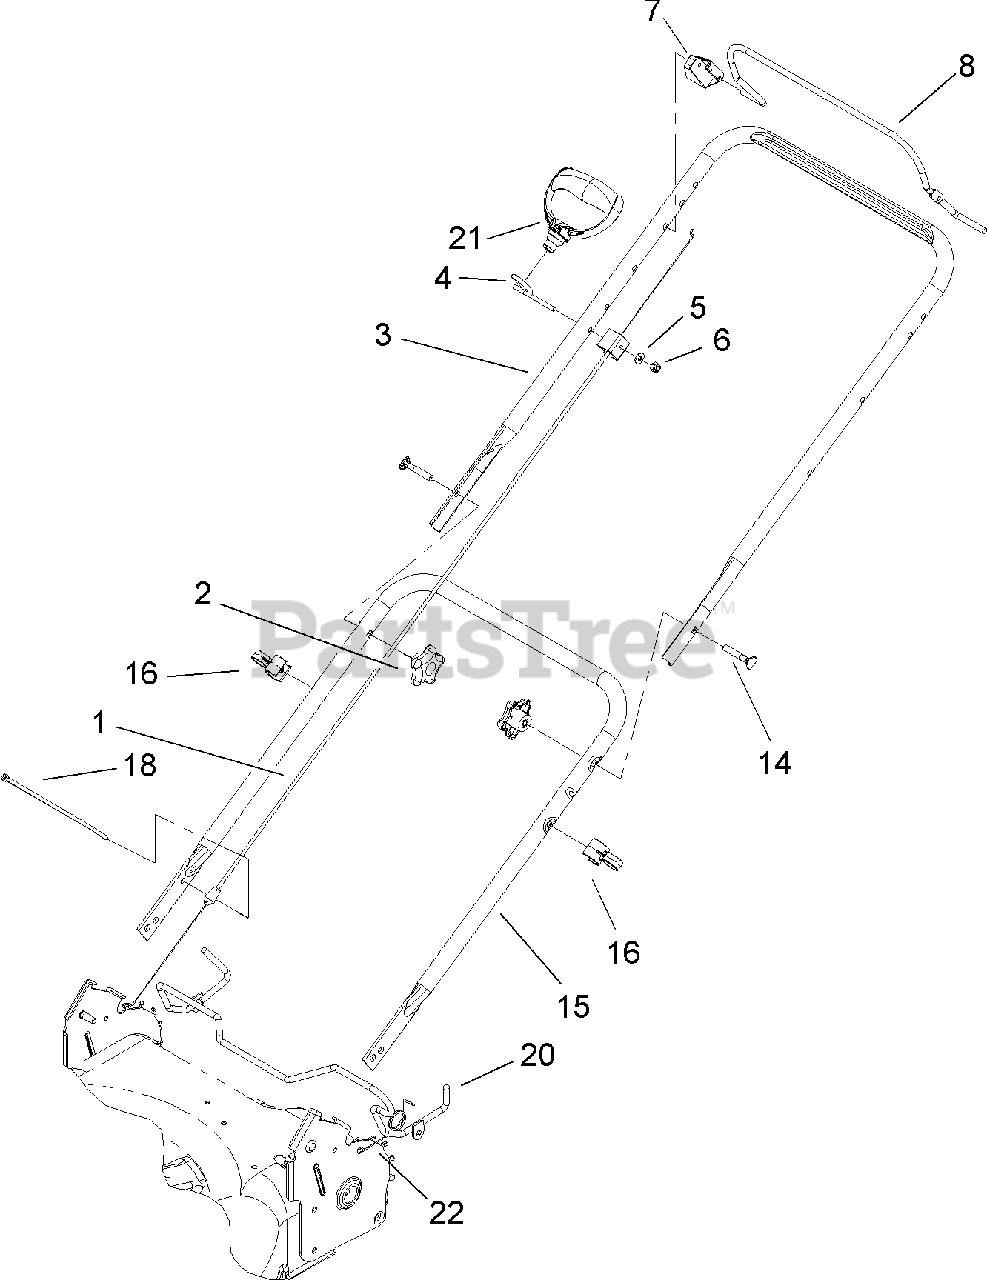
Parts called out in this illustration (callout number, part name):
1	CABLE-BRAKE, HP
2	KNOB-HANDLE
3	Handle-Upper
4	GUIDE-ROPE
5	WASHER-FLAT
6	NUT-LOCK, NI
7	STOP-PIVOT
8	BAIL-BRAKE
14	SCREW-HANDLE
15	HANDLE-LOWER
16	Guide-Cable
18	STRAP-TIE
20	RELEASE LEVER ASM
21	HANDLE-RECOIL
22	SPRING-TORSION
